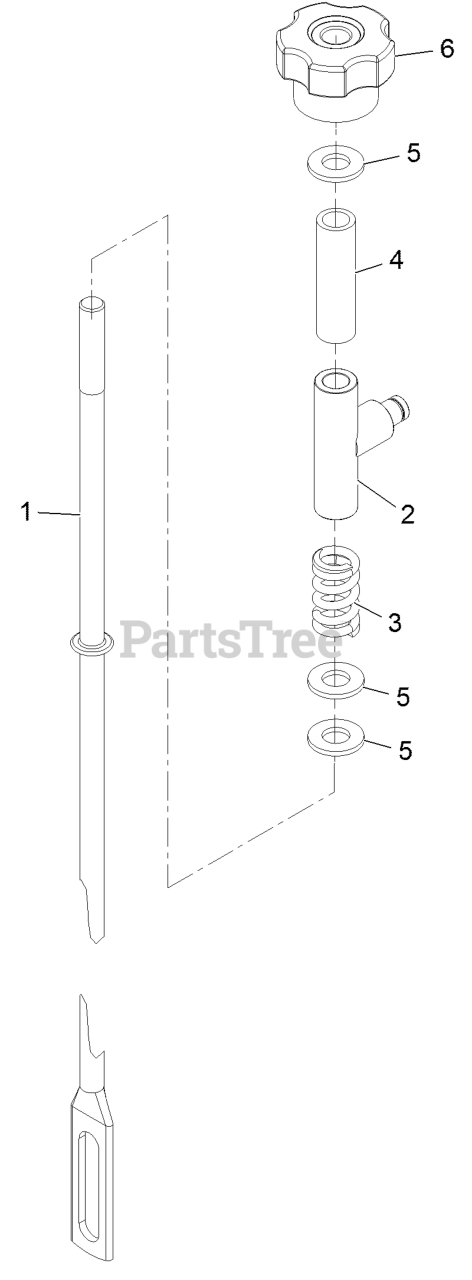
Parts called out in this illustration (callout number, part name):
1	ROD, RIGHT
3	SPRING, COMPRESSION
5	WASHER-FLAT
